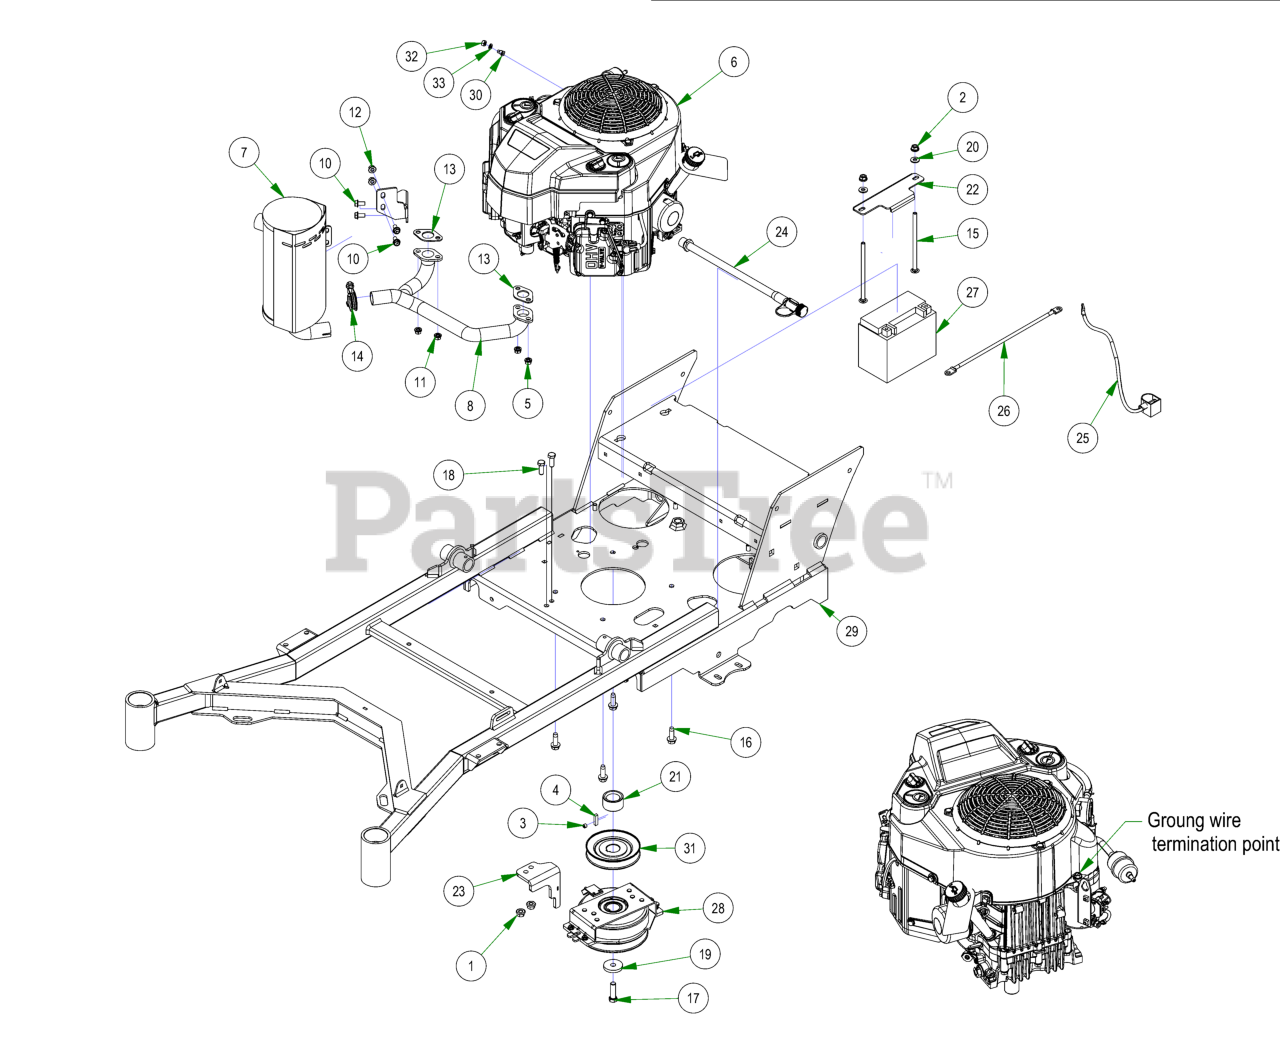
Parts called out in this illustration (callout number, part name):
1	3/8-16 NYLON INSERT FLANGE LOCKNUT (GR.F) ZINC
2	5/16-18 NYLON INSERT FLANGE LOCKNUT ZINC
3	5/16-24 X 1/4 SOCKET SET SCREW (CUP PT) PLAIN
4	1/4 X 1 SQ MACHINERY KEY 1018 STL PLN
5	M8-1.25 Zinc Nut
6	Kawasaki 18.5HP FS600 Electric Start
8	Exhaust Pipe
9	Exhaust Bracket
10	Exhaust Flange Bolt
11	Exhaust Lock Washer
12	Exhaust Nut
13	Exhaust Gasket
14	Exhaust Clamp
15	5/16-18 X 6 CARRIAGE BOLT (GR.5) ZINC
16	3/8-16 X 1-1/8HEX WASHER UNSLOT SERRATED (TRI-LOB) TRS ZINC YELLOW
17	7/16-20 X 1-1/2 HEX CAP SCREW (GR.8) w/ Patch
18	3/8-16 X 1 GR 5 Hex Bolts Zinc
19	CLUTCH WASHER
20	1/4 USS FLAT WASHER (3/4 OD) ZINC
21	1.130 x 1.75 x 1 Spacer, Countersunk, Zinc
22	Battery Hold Down Plate - Revolt
23	warner mgn clutch bracket v23
24	Kawasaki Oil Drain
25	24 inch Black Cable – MZ/ZT
26	12 in red battery cable
27	Interstate FAYTX14 Battery
29	2023 Walk Frame
30	Terminal 90 degree 6mm Spade
31	4 3/4" Motor Pulley
32	1/4-20 Hex Nut
33	1/4SPLIT LOCKWASHER ZINC
